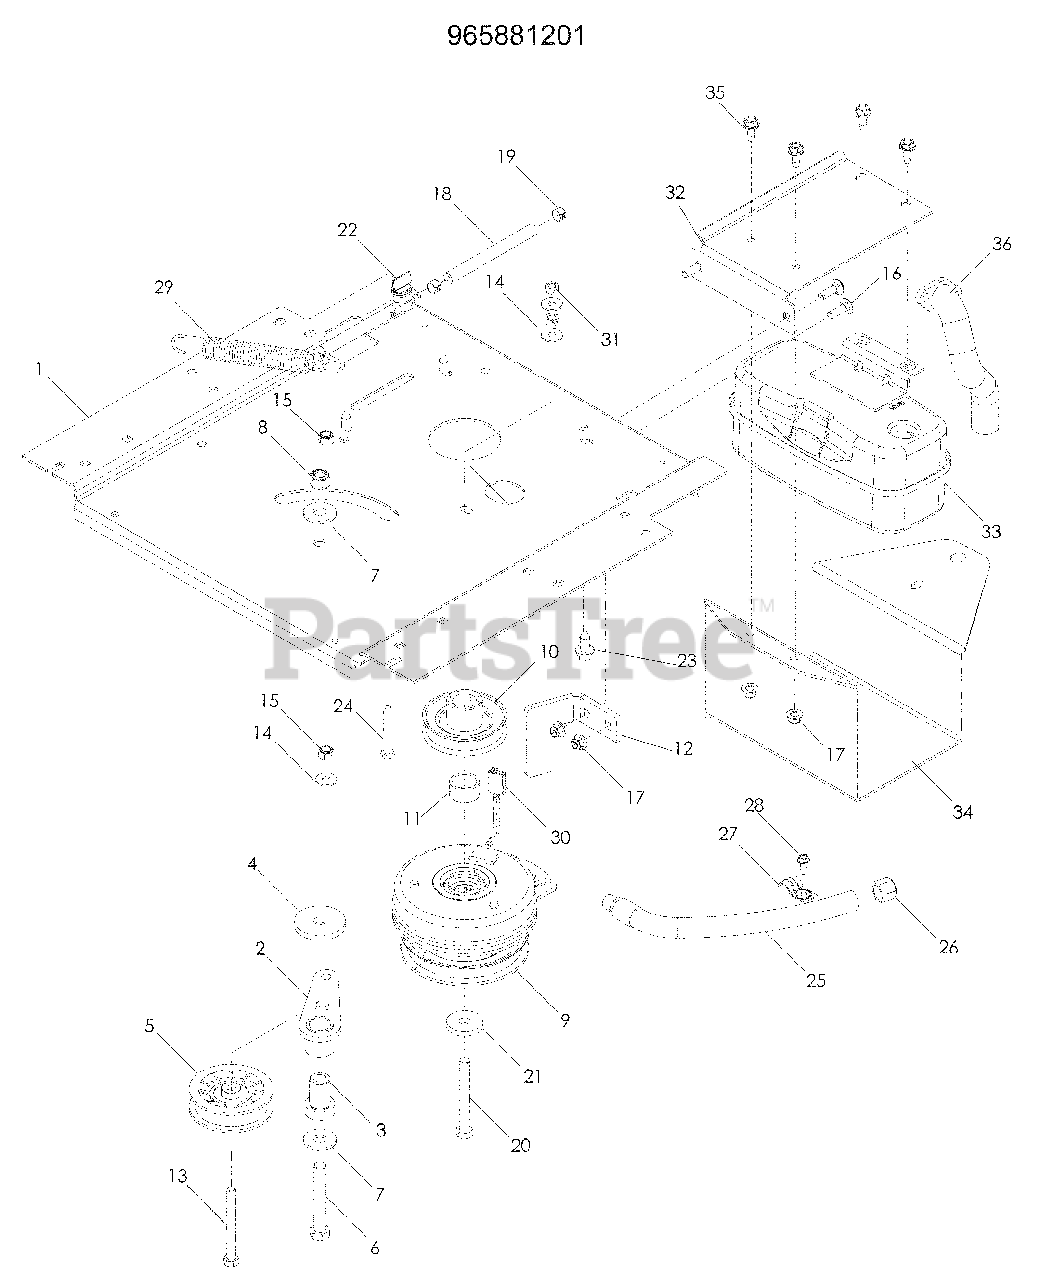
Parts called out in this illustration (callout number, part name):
1	PLATE, ENGINE
2	IDLER ARM
3	SPINDLE, IDLER
4	WASHER, HEAVY
5	PULLEY, IDLER
6	HCS ½-13 x 3¼
7	WASHER ½ FLAT
8	NUT ½ HEX NYLOC
10	PULLEY, ENGINE
12	STOP, CLUTCH
13	HCS 3/8-16 x 3½ TPBLT
14	WASHER 5/16 STD FLT
15	NUT 3/8-16 HEX NYLOC
16	RHSNB 5/16-18 x 1
17	NUT 5/16-18 FLANGE NYLOC
18	FUEL LINE 5"
19	HOSE CLAMP
20	HCS 7/16-20 x 3½
21	WASHER, CLUTCH
22	VALVE, FUEL
23	HHFS 3/8-16 x 1, THD FORM
24	HCS 5/16-18 x 2¼
25	HOSE, DRAIN
28	SCREW ¼-20 x 5/8 SLF TAP
29	SPRING, DECK DRIVE
30	HARNESS, CLUTCH
31	NUT 5/16-18 CTRLK
32	BRACKET, MUFFLER
34	GUARD, MUFFLER
35	BOLT 5/16-18 x ¾ THD FORM
36	TUBE, EXHAUST, KOHLER
